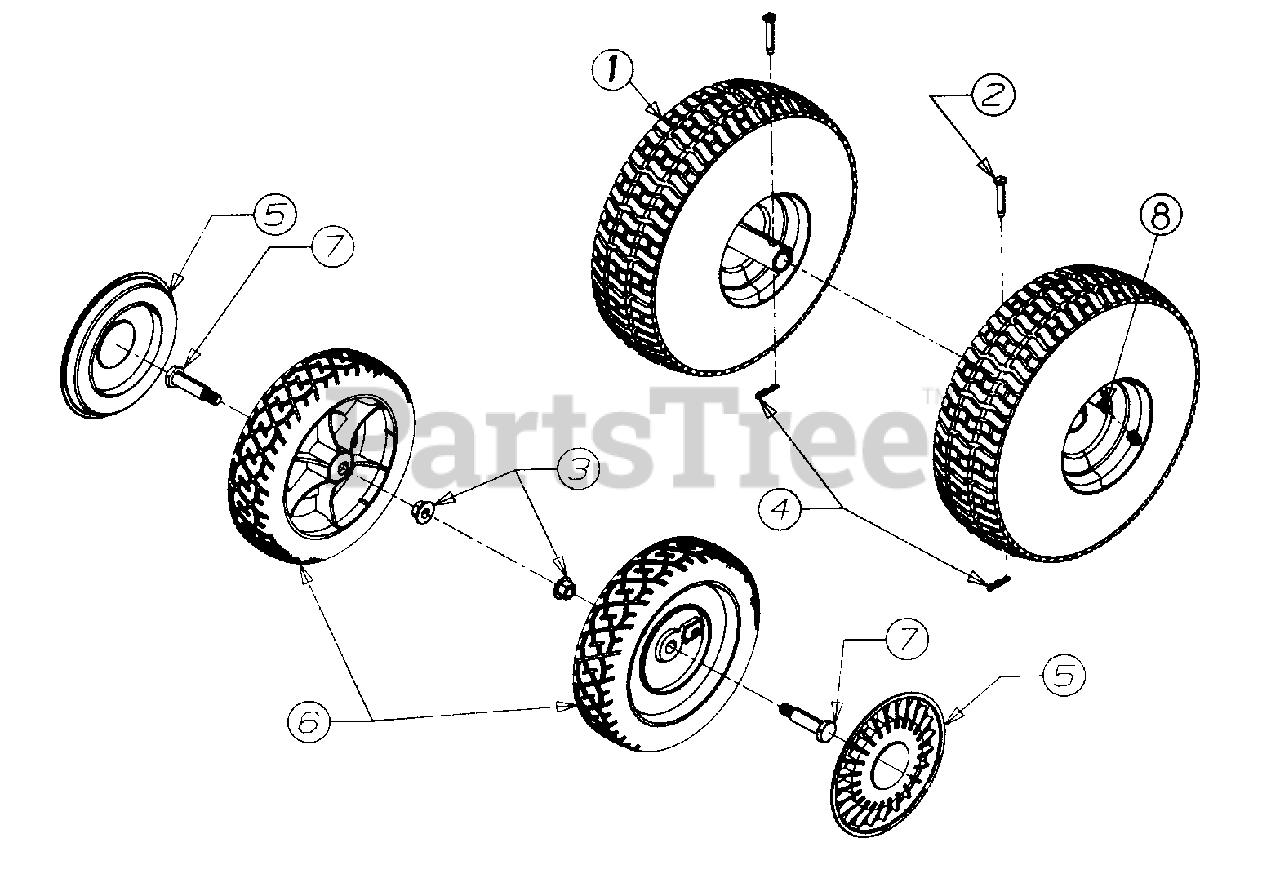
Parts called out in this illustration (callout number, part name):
1	WHEEL ASSY COMPLETE 4" X 10"
2	PIN - CLEVIS
3	NUT - HEX FLANGE
4	PIN - COTTER
5	HUB CAP
6	WHEEL 2" X 8"
7	SCREW - SHOULDER
8	VALVE STEM
